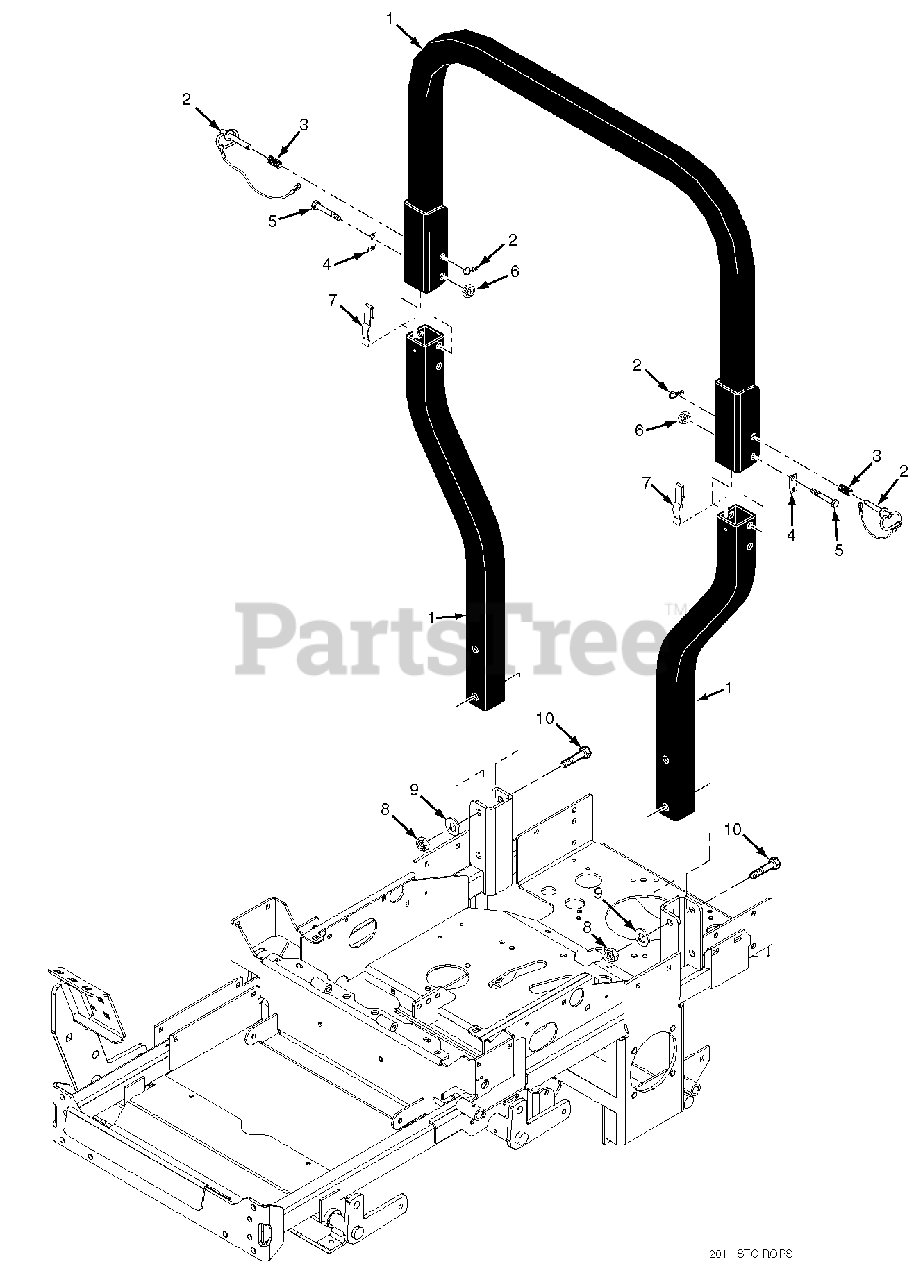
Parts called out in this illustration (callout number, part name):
1	STC Foldable ROPS
2	Pin Assembly
3	Spring, ROPS
4	Clip, ROPS
5	Bolt, Hex Head 1/2-13 x 3-1/4"
6	Nut, Center Lock 1/2-13
7	Spring Clip, ROPS
8	Nut, Center Lock 1/2-13
9	Flatwasher, 1/2-.562 x 1.375 x .109
10	Bolt, Hex Head 1/2-13 x 3-1/2"
